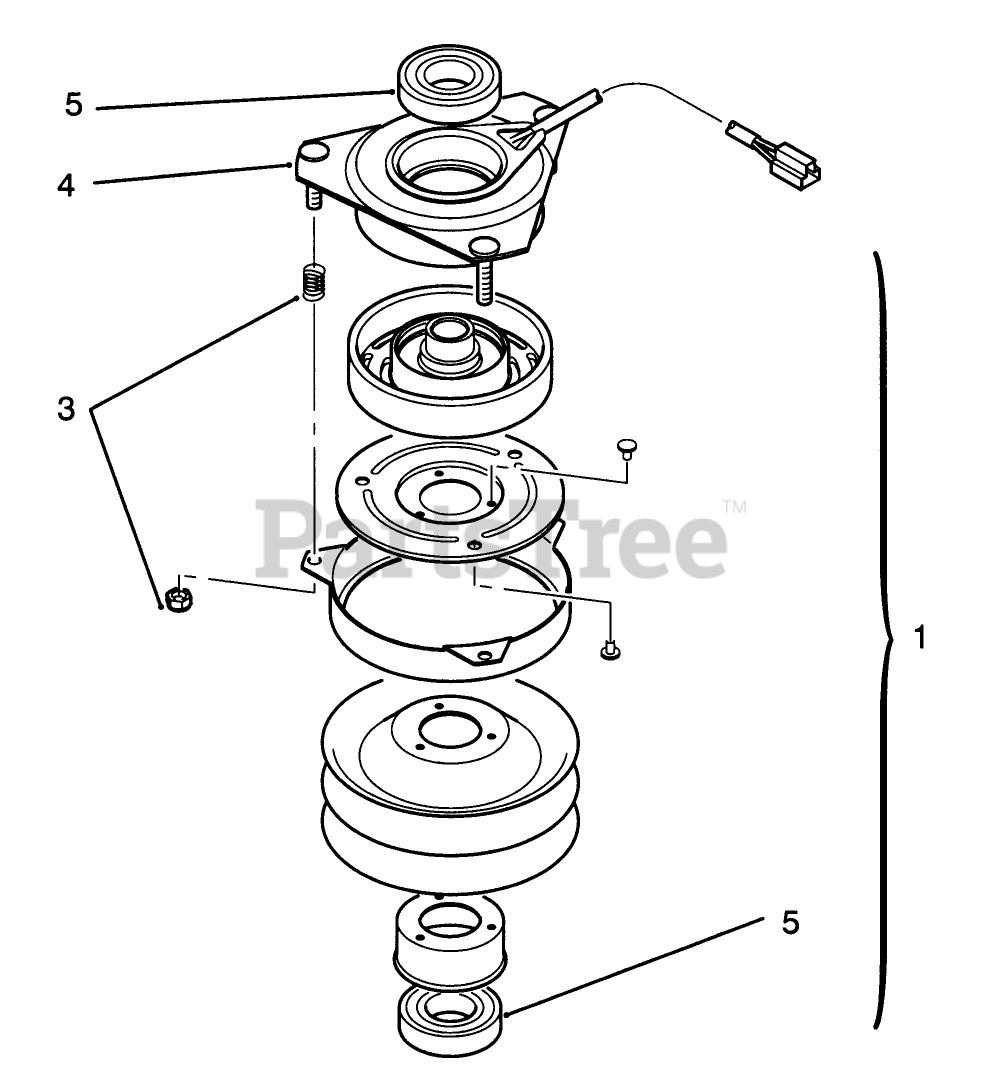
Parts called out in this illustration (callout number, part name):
1	ROTOR & ARMATURE ASSY
3	ACCESSORY PKG SRVC PART
4	FIELD ASSY (SRVC PART)
5	BEARING-ELEC CLUTCH
